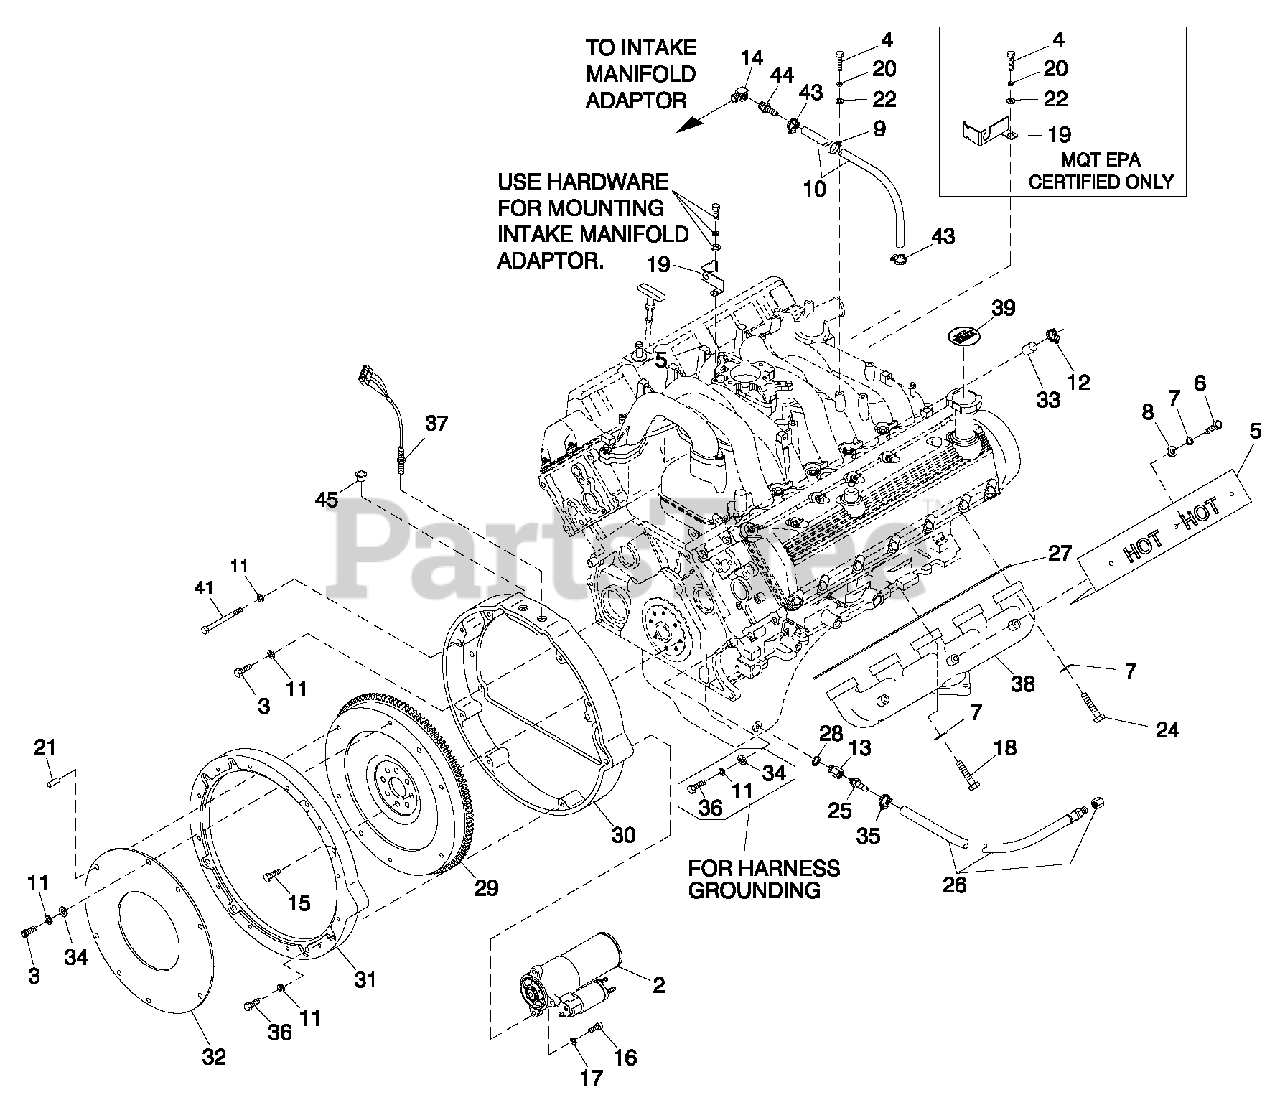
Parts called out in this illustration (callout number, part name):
2	STARTER MOTOR FORD V-10 ENGINE
3	SCREW SHC M10-1.5X 35 G12.9
4	SCREWHHCM6-1.0 X16G8.8
5	HEAT SHIELD EXHAUST
6	SCREW HHC 916-18X 1/2 SSTL
7	WASHER LOCK M8SSTL
8	WASHER FLATM8 SS
9	CLAMPVINYL .75X.343Z
10	HOSE COOL 5(8" ID 250)WP (14")
11	WAS HER LOCK M10
12	CLAM PHOSE #10.56 - 1.06 (2300 & 3000RPM UNTSONLY)
13	ADAPTERM14-1.50 X3/8NPT
14	ELBOW 90D 1/4 NPT F-M BRASS
15	SCREW HHCM10-1.0X 25 G10.9
16	SCREW SHC M8-1.25X30G12.9
17	WAS HER LOCK M8-5/16
18	SCREW HHCM 8-1.25 X 35 SSF-TH
19	BRACKETSIGNAL CONDITIONER
20	WAS HER LOCK M6-1/4
21	DOWEL PIN M10X24
22	WAS HER FLAT 1/4 ZINC
23	TIE WRAP UL7.4" X .19" BLK (NOTSHOWN)
24	SCREW SHC M8-1.25X35SS
25	BARBED STR 3/8NPTX3/8
26	HOSE DRAIN ASSY 28"
27	GASKET EXHAUST MANIFOLD
28	WAS HER NYLON .565
29	ASSEMBLY 68L G-BOX FLYWHEEL
30	FLYWHEELHOUSINGMACH6.8LV10
31	COVER FLYWHEEL MACH 6.8L V-10
32	PLATE DAMPNER RETNR
33	CAP HOSE (2300 & 3000RPM UMTS ONLY)
34	WAS HER FLAT 3/8-M10 ZINC
35	CLAM PHOSE .38-.87
36	SCREW SHC M10-1.5X 25 G12.9
37	ASSY MAG PI CK U P(3/8-24 M ALE)
38	EXH MAN FOLD MACH 6.8L V-10
39	DECAL REFER TO OWNERS MANUAL
41	SCREWSHC M10-1.50X 100 G10.9
43	CLAM PHOSE #10.56-1.06
44	BARBED STR 1/4NPTX 5/8
45	PLUG PLASTIC 3/8 NPT
